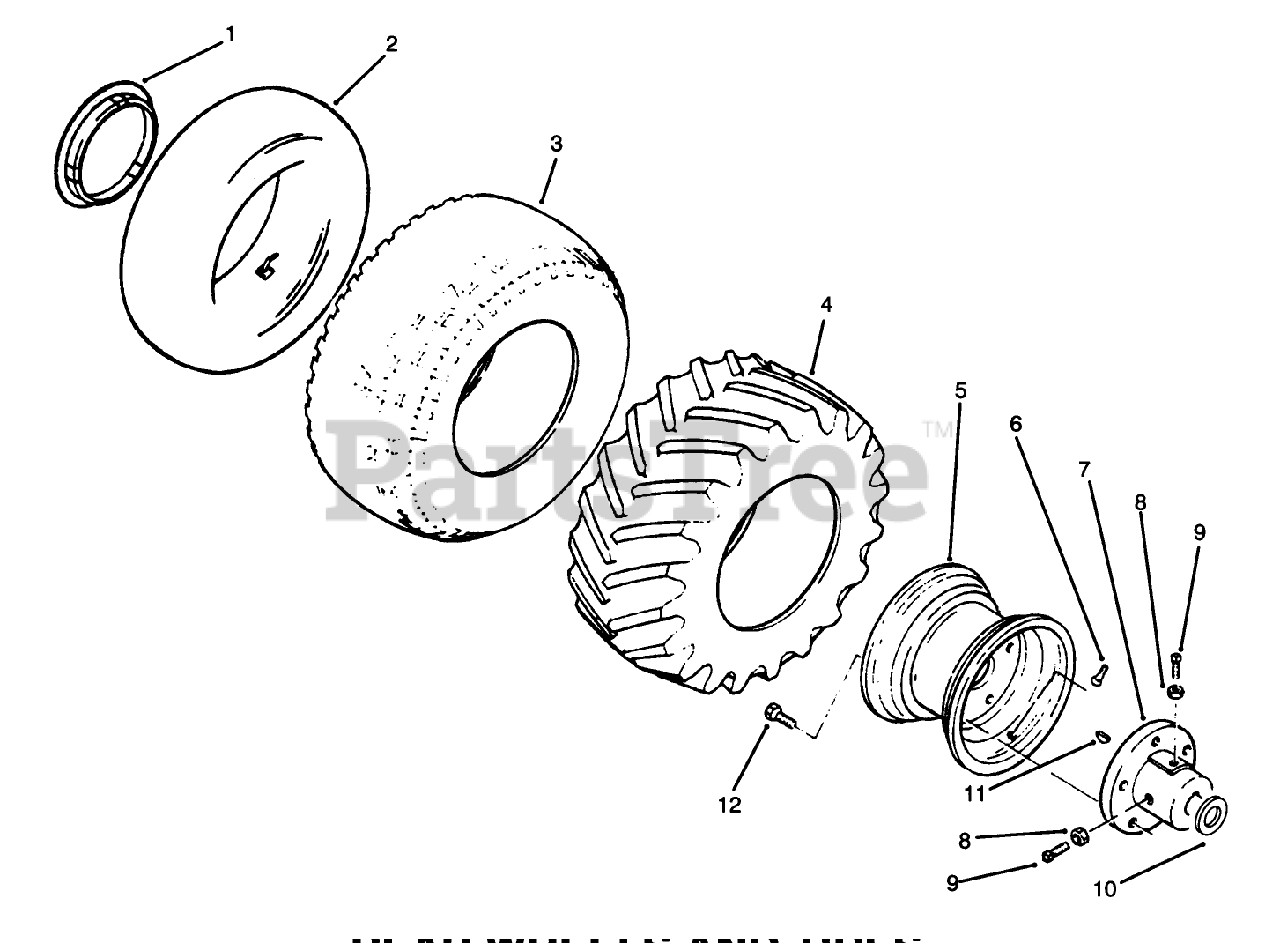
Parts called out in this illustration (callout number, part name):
5	WHEEL
6	VALVE
8	NUT-JAM
9	SCREW-SET, SQH
10	WASHER-THRUST
11	KEY-WOODRUFF
12	BOLT-LUG
